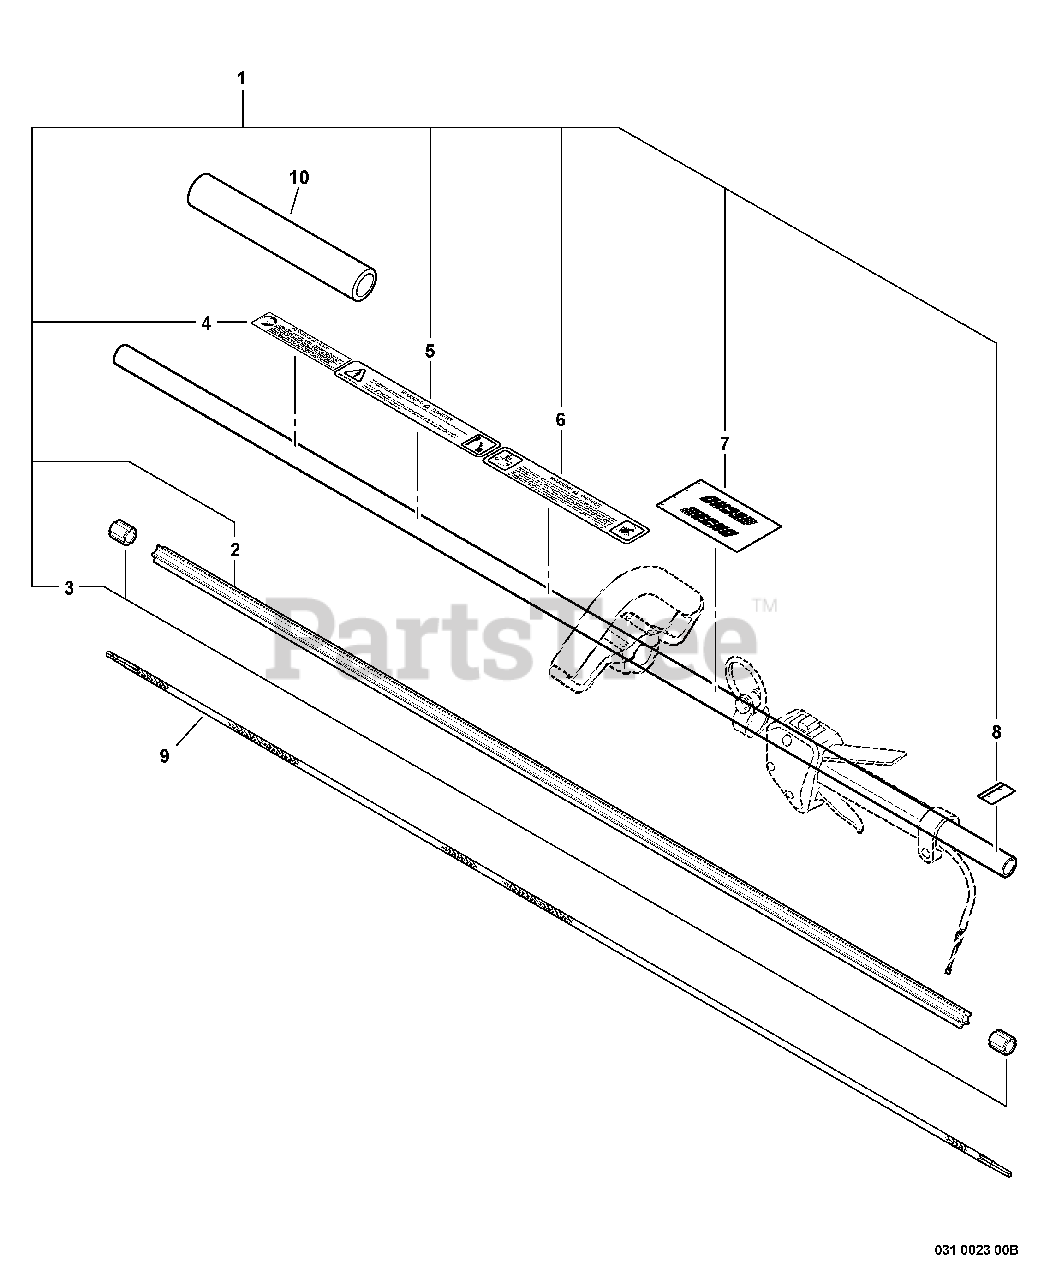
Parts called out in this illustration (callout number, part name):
1	MAIN PIPE ASSY
2	LINER - FLEXIBLE
4	LABEL - CAUTION -- SPANISH
5	LABEL - CAUTION
6	LABEL - CAUTION
7	LABEL - HANDLE LOCATION
8	LABEL - ALIGNMENT
9	DRIVESHAFT - FLEXIBLE
10	GRIP, HANDLE
